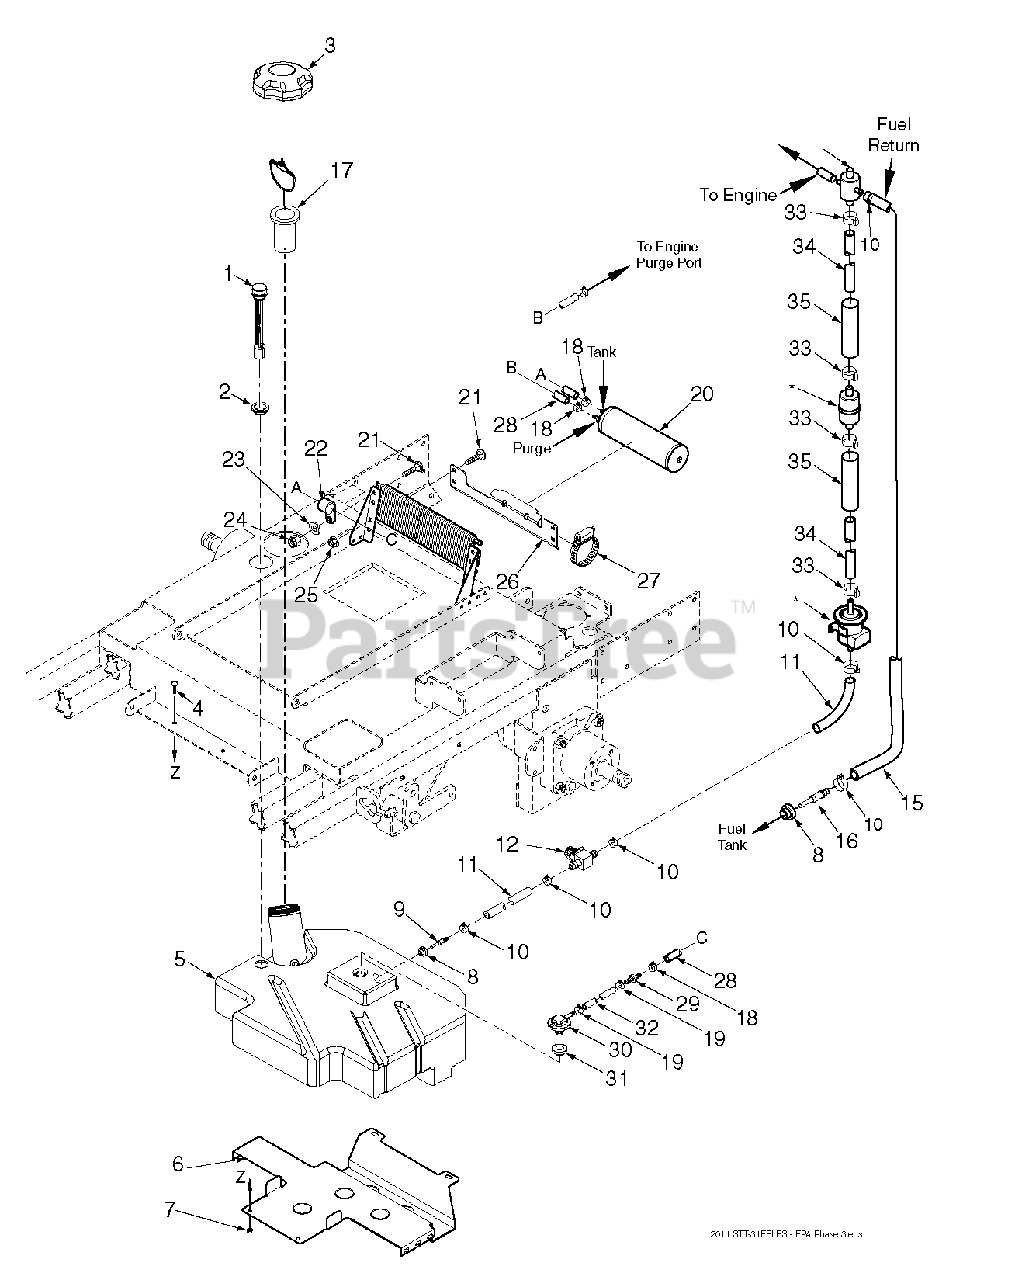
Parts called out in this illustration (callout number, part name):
1	Fuel Gauge Assembly
2	Seal, Fuel Gauge
3	Fuel Cap, Tethered
4	Bolt, Carriage 1/4-20 x 3/4"
5	Fuel Tank Assembly - STT
6	Support Bracket, Fuel Tank
7	Nut, 1/4-20 Serrated Flange
8	Bushing, .56 Dia. Viton
9	Hose Fitting
10	Clamp, Fuel Hose 5/16" I.D.
11	Fuel Hose, 5/16" I.D. Non-Perm
12	Valve, Fuel Shut-Off
13	Clamp, .87" Max. Dia
14	Fuel Hose, 1/2" I.D. Non-Perm
15	Fuel Hose, 1/4" I.D. Non-Perm
16	Return Fitting, Straight
17	Tube, Fuel Tank Insert - 6"
18	Clamp, Vapor Recovery Hose 3/16"
19	Clamp, Fuel Hose 7/32 ID
20	Carbon Canister
21	Bolt, Carriage 1/4-20 x 3/4"
23	Flatwasher, 1/4-.281 x .562 x .049
24	Nut, 1/4-20 Elastic Stop
25	Nut, 1/4-20 Serrated Flange
26	Bracket, RH Canister Mounting
28	Hose, 3/16
29	Mender, 1/4 x 3/16 w/.02 Hole
30	Valve, Rollover
31	Grommet, Viton
32	Hose, 1/4" Vapor Recovery
33	Fuel Clamp, 5/16" Oetiker
34	Fuel Hose, 5/16" Non-Perm
35	Shield, Flexible
36	Regulator Assembly, Fuel Pressure
